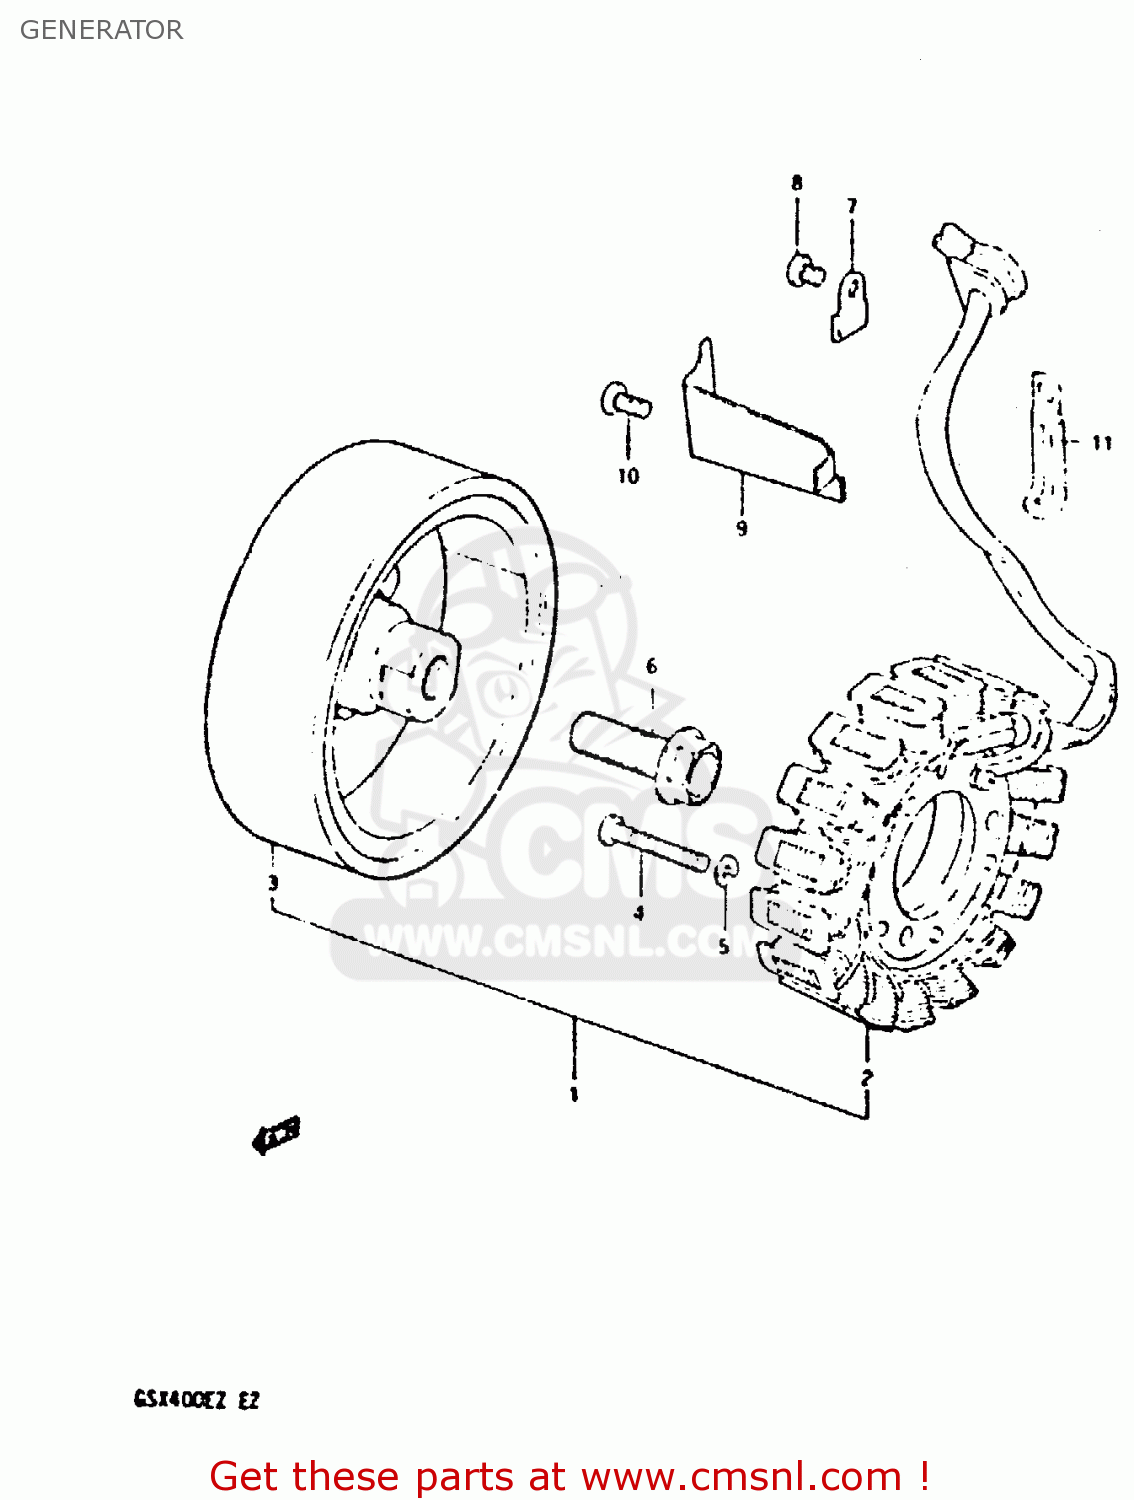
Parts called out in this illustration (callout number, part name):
1	GENERATOR ASSEMBLY
2	STATOR ASSEMBLY
3	ROTOR ASSEMBLY
4	SCREW
5	LOCK WASHER
6	BOLT(12X40)
7	CLAMP,GENERATOR LEAD WIRE
8	SCREW
9	CLAMP,GENERATOR LEAD WIRE
10	SCREW
11	CLAMP L:35
